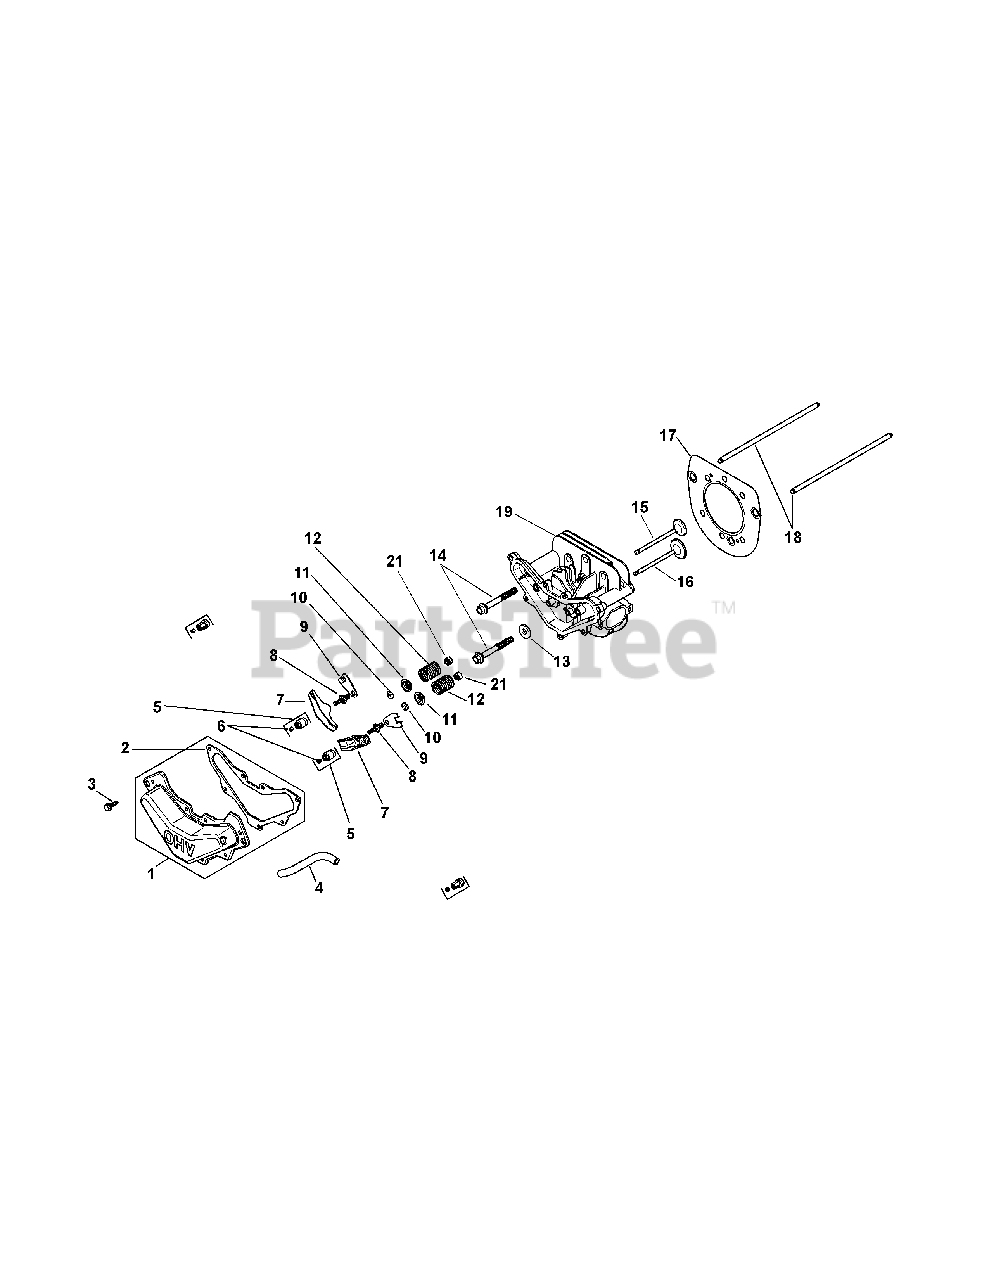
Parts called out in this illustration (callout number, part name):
1	Valve Cover Kit (Inc. 2)
2	Valve Cover Gasket
3	Flg. Thd. Frm. Screw, M6 x 1.0 x 20
4	Breather Hose
5	Rocker Pivot Assembly (Inc. 6)
9	Push Rod Guide Plate
10	Retainer Lock
11	Valve Spring Cap
13	Flat Washer, 13/32
14	Flange Screw, M10 x 1.5 x 80
15	Exhaust Valve
16	Valve, Exhaust Valve
17	Cylinder Head Gasket Kit
17	Carburetor Gasket
17	Air Cleaner Base Gasket
17	Exhaust Gasket
17	Heat Deflector Gasket
17	Hex Socket Head Cap Screw
17	Spring Lock Washer, 5/16
19	Kit, Cylinder Head
21	Valve Stem Seal
